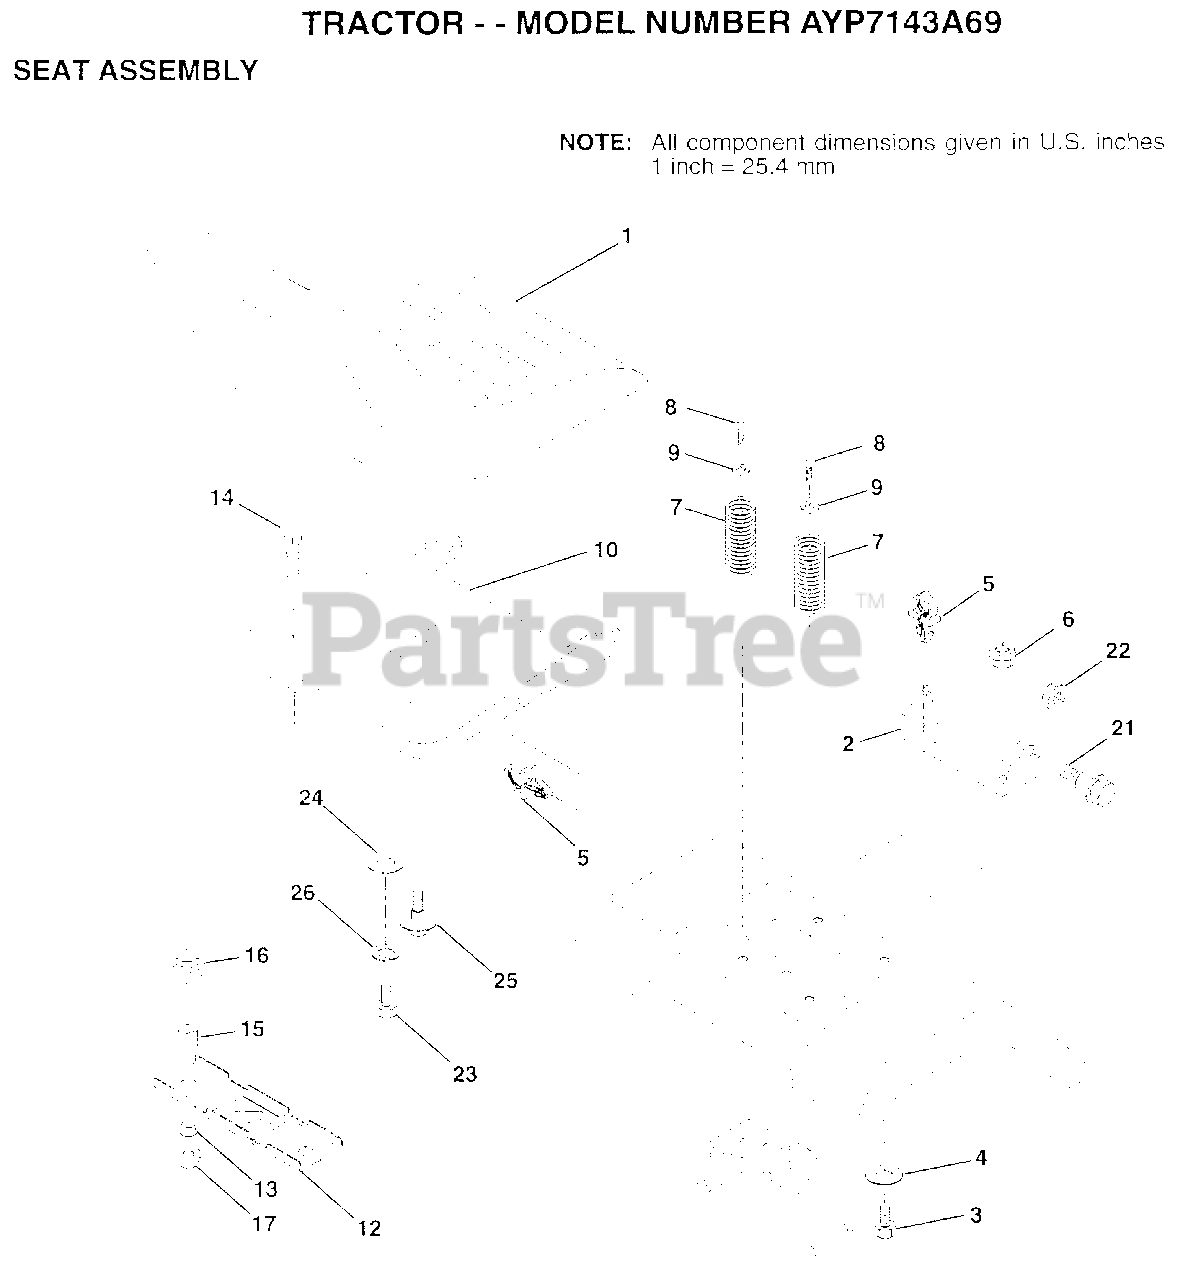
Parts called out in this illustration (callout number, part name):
2	BRACKET PVT SEAT
3	BOLT
4	WASHER PM
5	CLIP.PUSH-IN.HING
6	NUT
7	SPRING COMPRESSIO
8	SCREW GTV
9	WASHER
12	BRKT SWITCH
13	BUSHING
15	SPLIT SPACER
16	SPRING
21	BOLT.SHLD.5/16-18
22	NUT
23	BOLT
24	WASHER
25	"BOLT,SHOULDER"
26	LOCKWASHER
